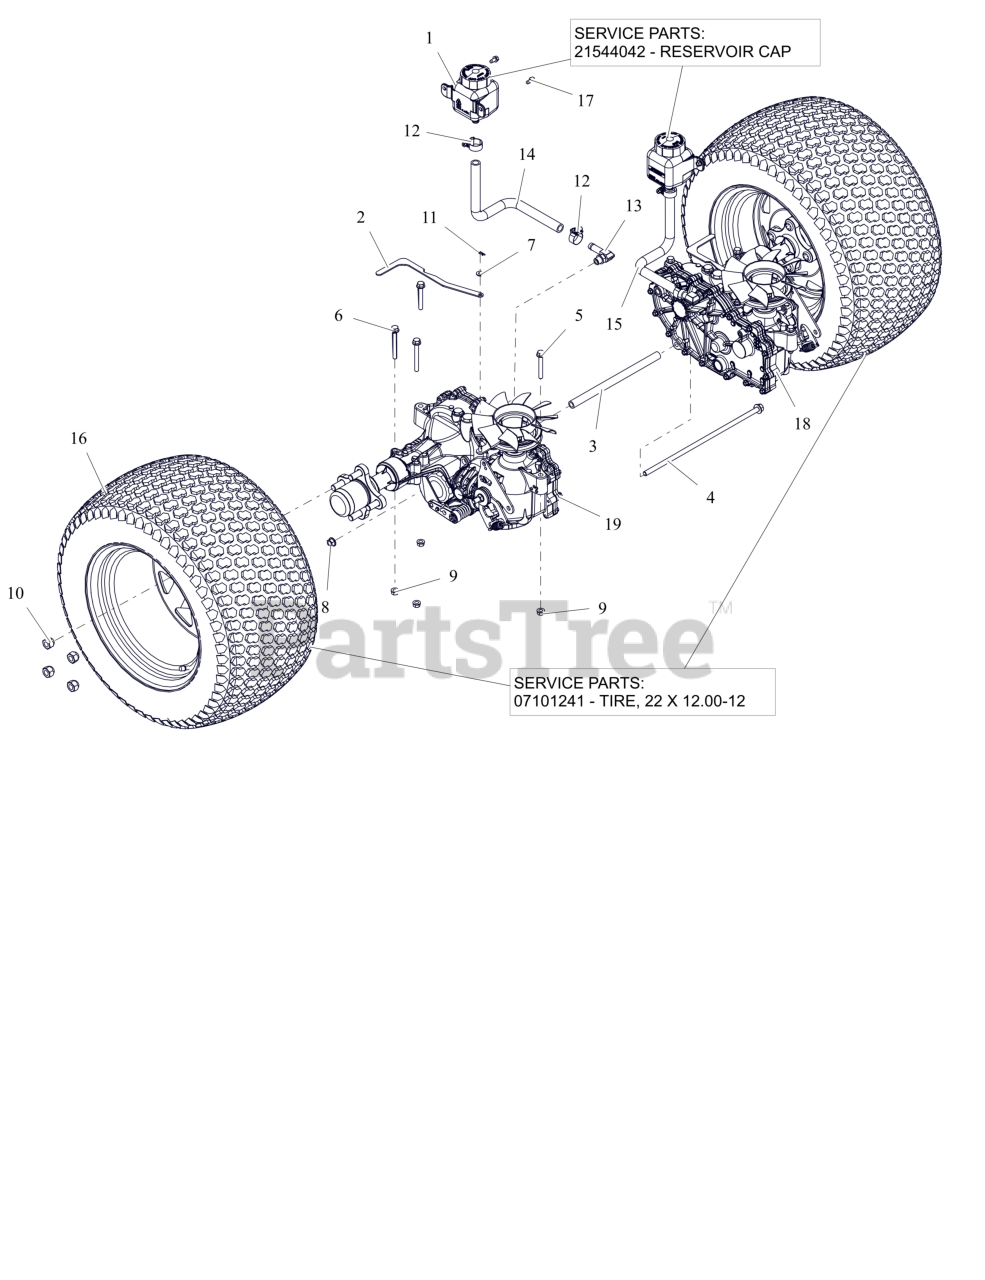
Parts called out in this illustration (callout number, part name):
1	TANK, EXPANSION
1	CAP, HYDRO RESERVOIR REPLAC.
2	BRKT, VALVE DUM
3	SPCR, TRANSAXLE .406 ID X .630 OD X 9.95LG (BLACK)
4	BLT, HEX-FLG 0.375-16X13 GR5 ZC120
5	BLT,HEX-FLG .31-18X2.25 G5 ZCC
6	BLT,HEX-FLG .31-18X2.75 G5 ZCC
7	WSHR,FLT .281X.625X.065 ZCC
8	NUT-LK-TOP-FLG .38-16 ZC120
9	NUT,LK-CTR-FLG .31-18 GF ZCC
10	NUT, WHEEL .50-20 ZCC
11	PIN, HAIR #225 .072X1.09
12	CLAMP,.88 DIA. HOSE
13	FITTING, HYD (90 DEG)
14	HOSE, FORMED EXPANSION -HD RH
15	HOSE, FORMED EXPANSION -HD LH
16	ASM, WHL/TIRE 22X12.00-12 K500
16	TIRE, 22X12.00-12
16	TUBE 22,23&24X8.50/9.50/10.00/10.50/12.00-12
17	SCR-TAP .25-20X.50 HWH ZCC
18	TRANSAXLE, ZT3100 - LH
19	TRANSAXLE, ZT3100 - RH
